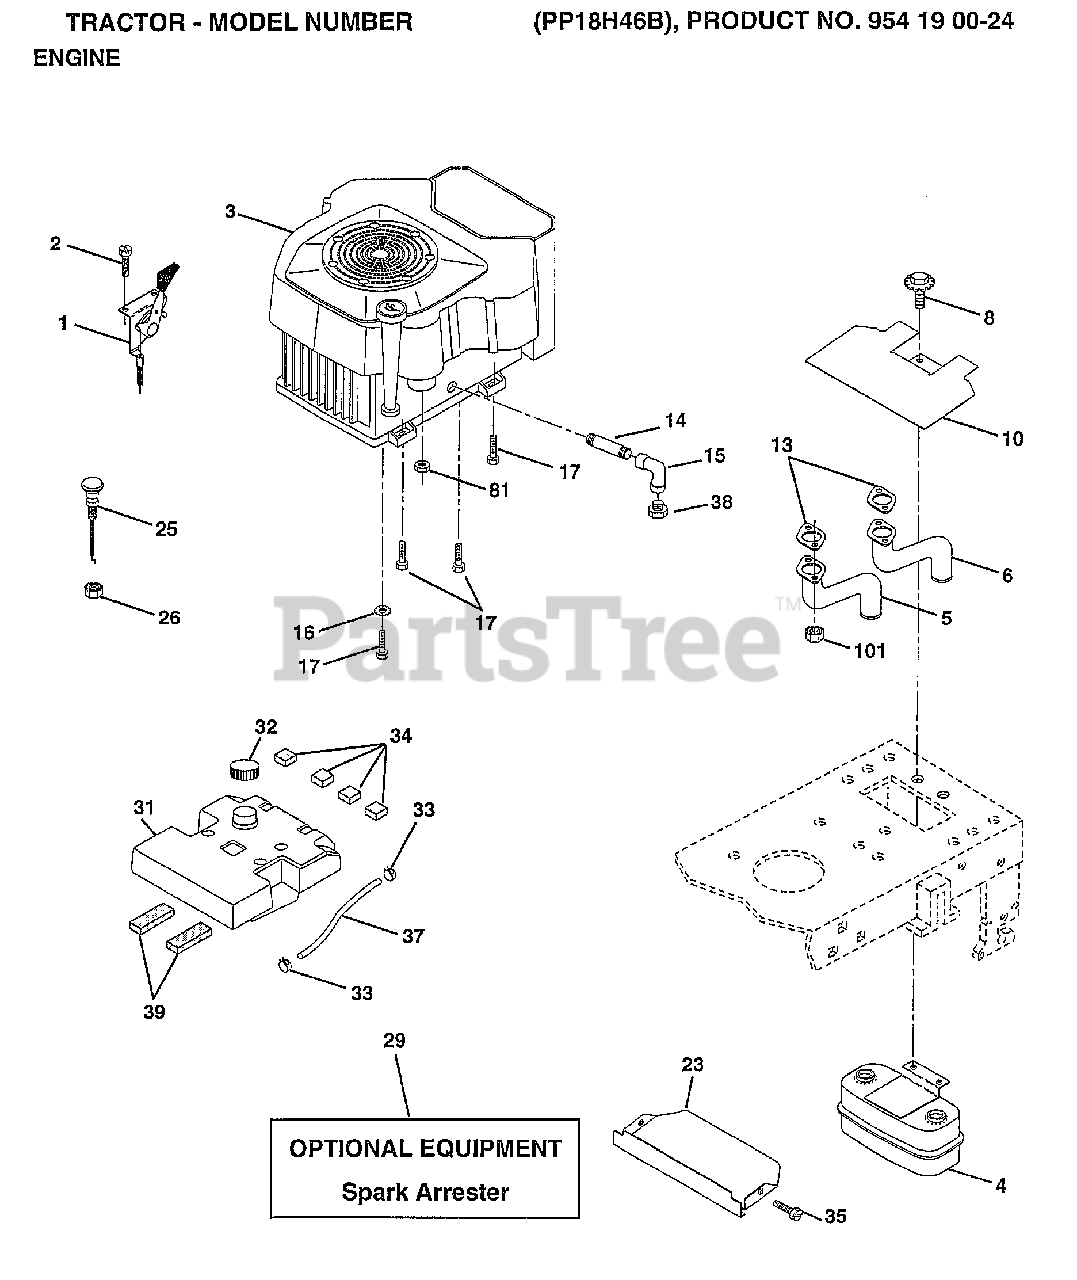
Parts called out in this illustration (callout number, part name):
2	SCREW LT
4	MUFFLER.TW.LOTONE
5	PIPE-EXHAUST.LH
6	PIPE-EXHAUST.RH.
8	BOLT.5/16-18.UNC
10	SHIELD.HEAT.MUFF.
13	GASKET
14	PIPE NIPPLE LT
15	ELBOW
16	LOCKWASHER
17	SCREW LT
23	SHIELD.BRN/DBR.GD
25	CONTROL.CHOKE.37
26	"NUT,KEPS 3/8-24IM"
31	"TANK.FUEL,3.5 GAL"
32	CAP ASM FUEL
33	HOSE CLAMP
34	PAD-SPACER LT
35	SCREW
37	FUEL LINE T
39	PAD IDLER TI
81	NUT
101	NUT FLANGE M8-125
